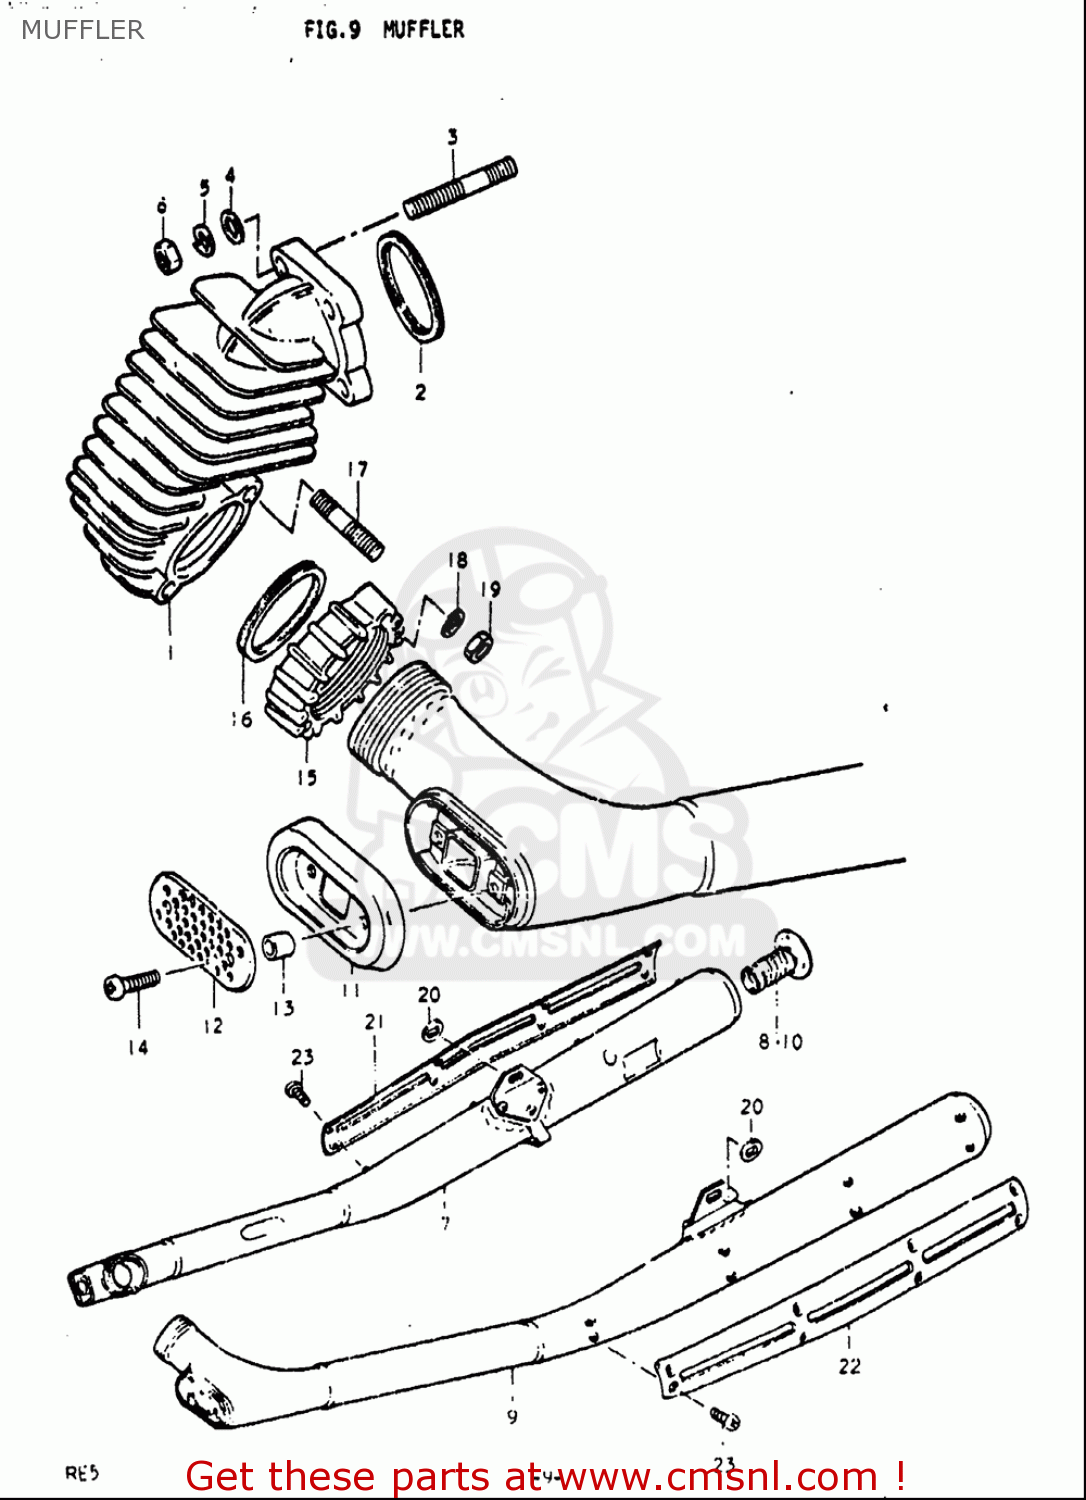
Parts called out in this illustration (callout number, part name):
2	GASKET,EXHAUST PIPE,R (NAS)
3	BOLT,STUD
4	WASHER
5	WASHER,LOCK
6	NUT
15	GASKET,EXHAUST PIPE,R (NAS)
17	BOLT,STUD
18	WASHER,LOCK
19	NUT
23	SCREW
